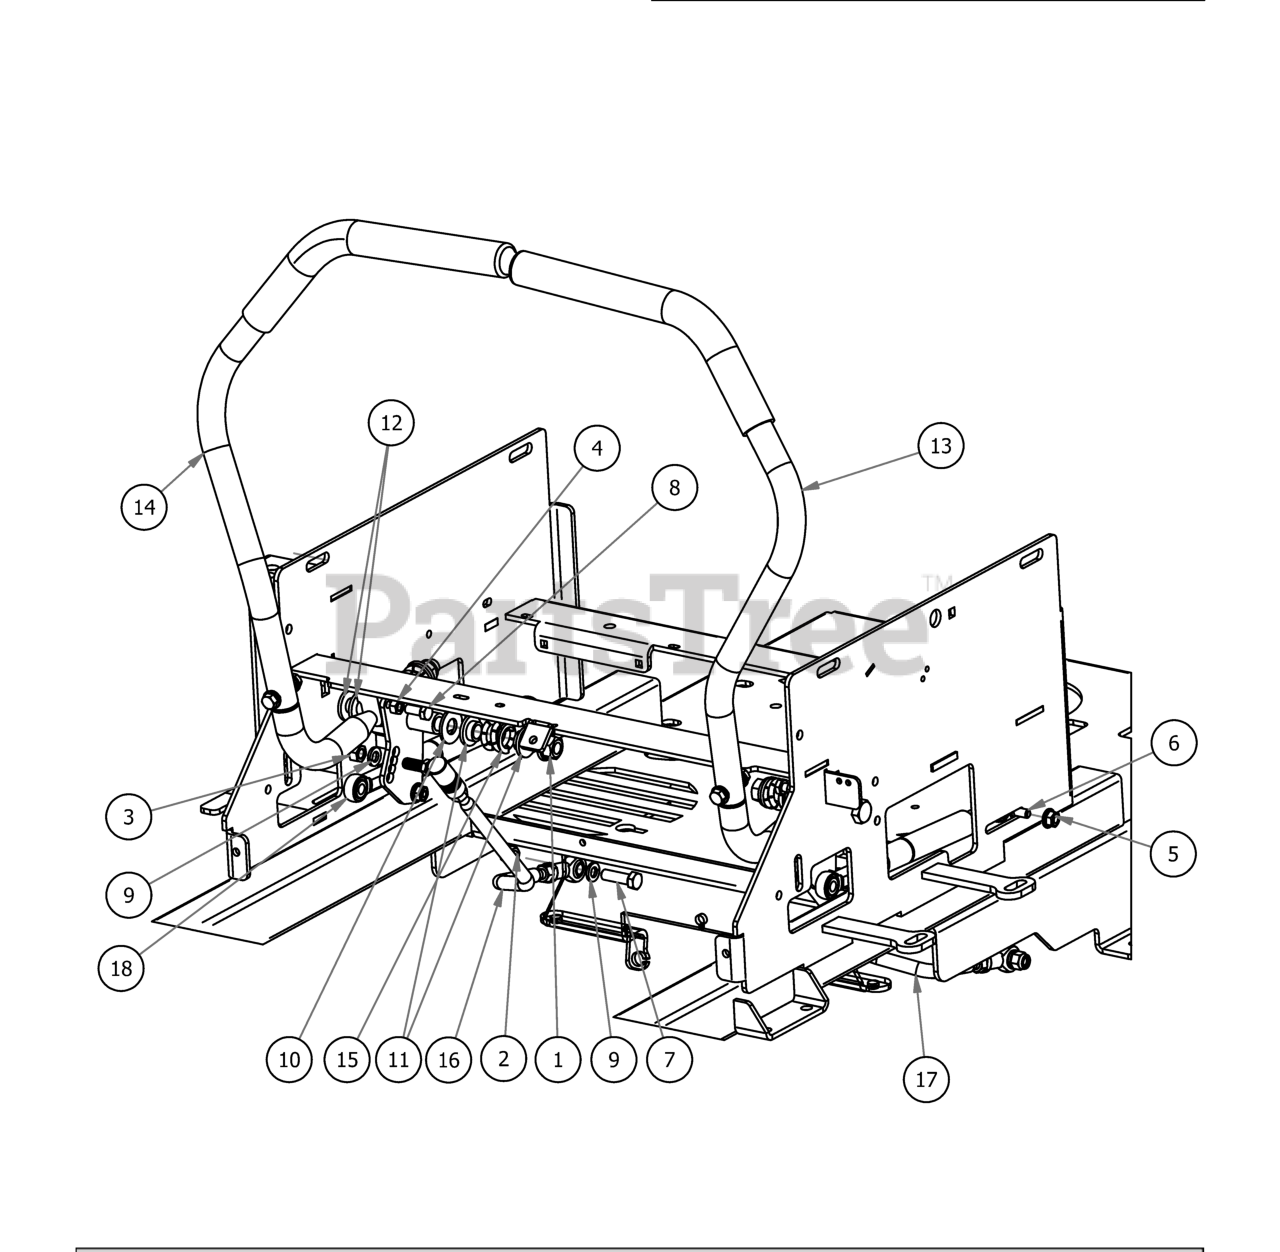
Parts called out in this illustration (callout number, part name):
1	1/2-13 Mechanical Lock Nut
2	3/8 Nylock Nut
3	3/8" Fine Threaded Jam Nut
5	5/16" Flange Nut
6	10mm Damper Ball Stud-Steering
7	3/8" x 1 1/4" Hex Bolt
8	5/16" x 3/4" Hex Bolt
9	3/8" Lock Washer
10	1/2" Washer (Grade 8)
11	.515 ID Nylon Shoulder Washer
12	.505 Nylon Spacer
13	ZT Steering Arm Assembly, Left Hand
14	ZT Steering Arm Assembly-Right Hand
15	Drive Lever Spring
16	Push Rod-Right
17	Push Rod-Left
18	Steering Damper
